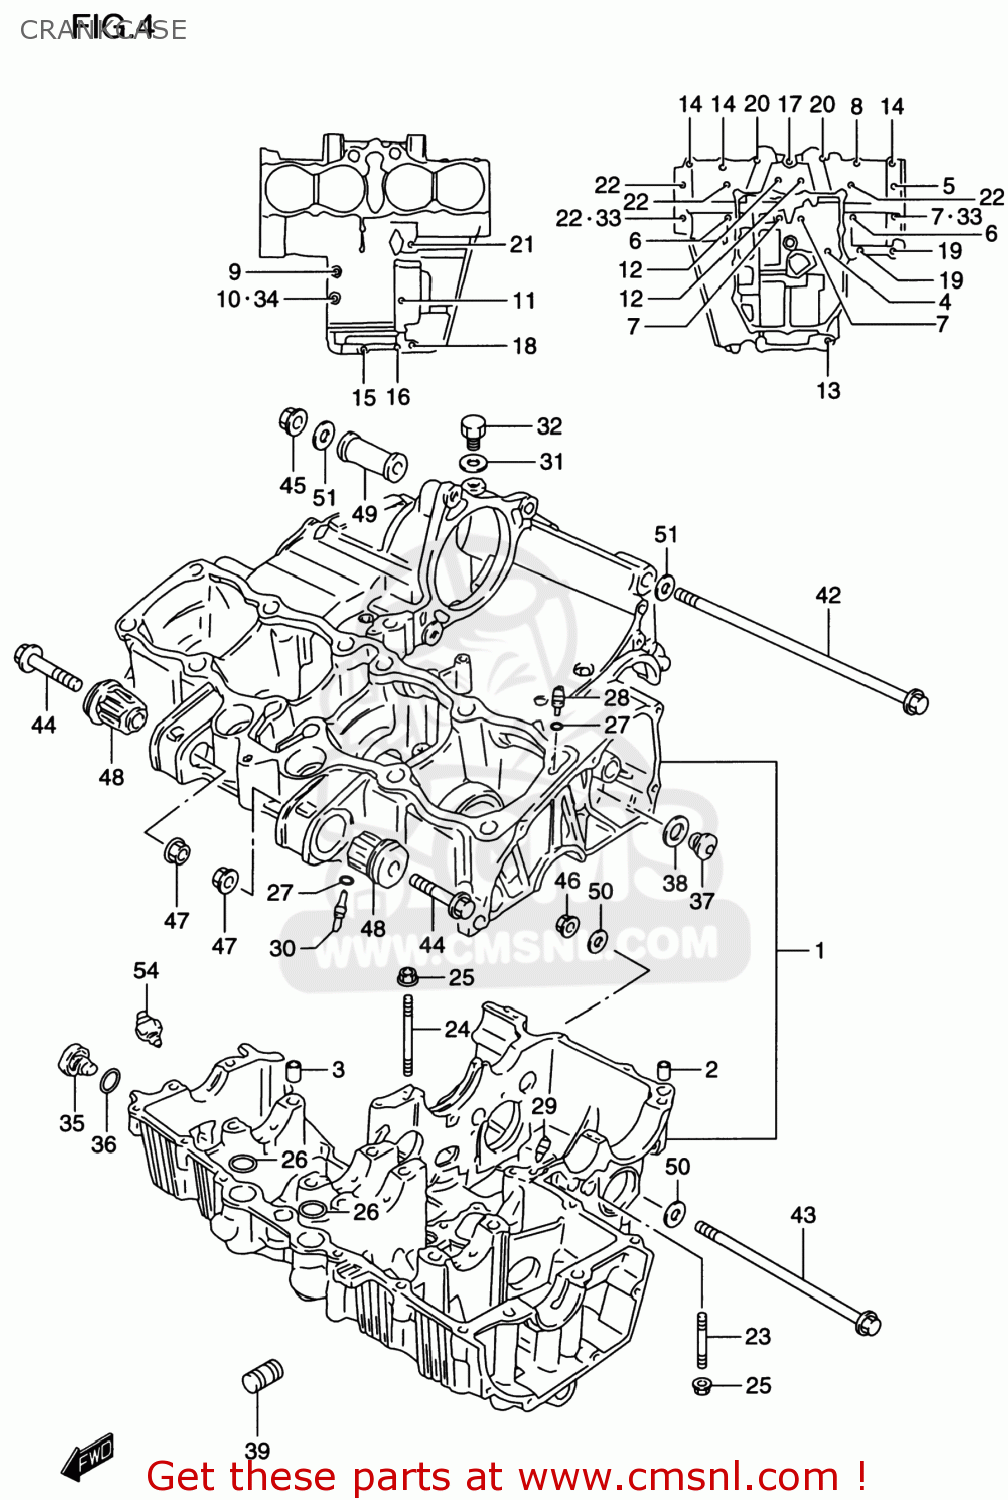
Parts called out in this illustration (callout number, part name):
1	CRANKCASE SET
2	PIN(10.4X13X22)
3	PIN(8.4X11X20)
4	BOLT(6X105)
5	BOLT(8X105)
6	BOLT(8X125)
7	BOLT(8X115)
8	BOLT
9	BOLT
10	BOLT
11	BOLT
12	BOLT
13	BOLT
14	BOLT
15	BOLT
16	BOLT
17	BOLT
18	BOLT
19	BOLT, HYDRAULIC UNIT NO.2
20	BOLT
21	BOLT
22	BOLT(8X95)
23	STUD BOLT
24	STUD BOLT
25	NUT
26	O RING(D:2.5,ID:21)
27	O RING(D:1.2,ID:4)
28	JET,AIR
29	JET
30	JET(13)
31	GASKET(12.1X16.2X3.7) (NAS)
32	PLUG(12X9)
33	GASKET(8.5X17X2.3) (NAS)
34	GASKET(6.2X13X1.2) (NAS)
35	PLUG
36	O RING(D:2.4,ID:16.8)
37	PLUG
38	GASKET(13.8X18.8X4.8) (NAS)
39	UNION,OIL STAND
40	BEARING,CRANK THRUST(GREEN)
41	BEARING,CRANK THRUST(RED)
42	BOLT(10X180)
43	BOLT
44	BOLT,ENGINE MOUNTING (10X5)
45	NUT
46	NUT 12MM
47	NUT
48	BUSH,ENGINE MOUNTING
49	SPACER,ENGINE MOUNT(L27)
50	WASHER
51	WASHER
52	SWITCH ASSEMBLY,OIL PRESSURE
